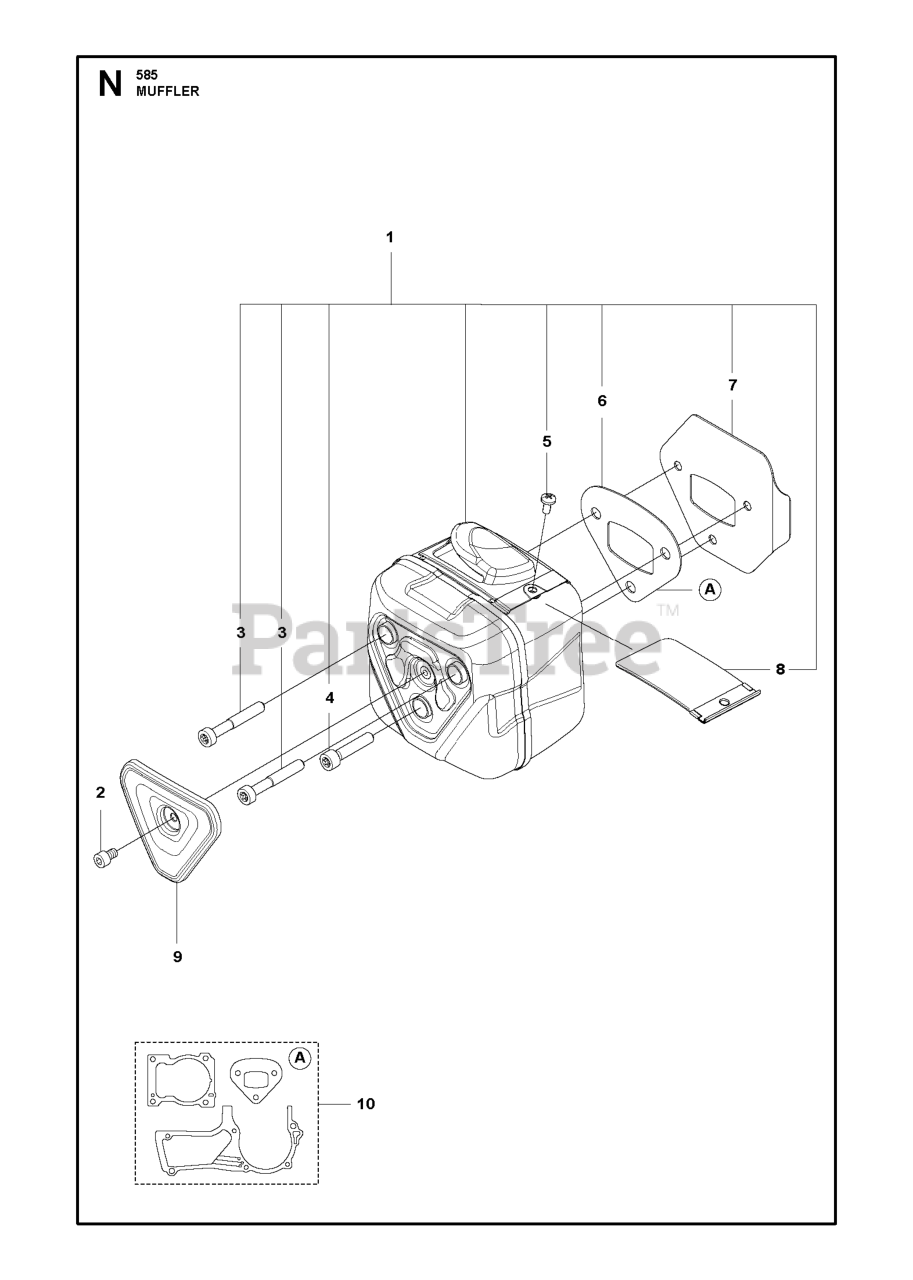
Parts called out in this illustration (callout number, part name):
1	MUFFLER KIT 90CC PRO
2	SCREW ISO 4762 M4X8-A4-80 BUMA
3	SCREW ITXSCM M6X40/25 T27 12.
4	SCREW ISO 14579 M 6 X 30 12.9
6	GASKET 90CC PRO
7	HEAT DEFLECTOR 90CC PRO
8	SPARK ARRESTER 90CC PRO
9	CRASH GUARD 90CC PRO
10	GASKET KIT 90 CC SPARE PART
